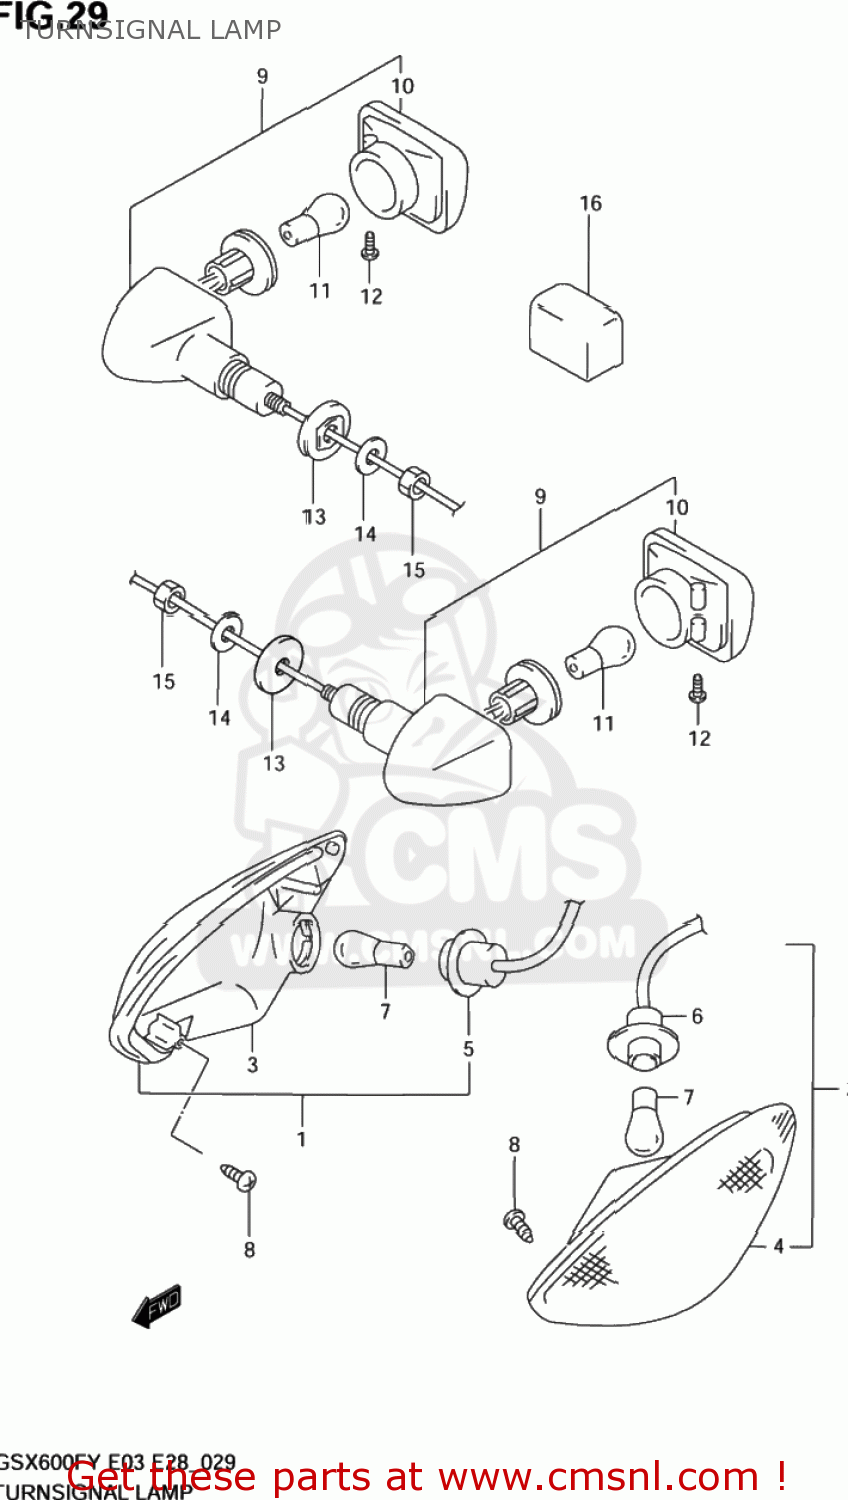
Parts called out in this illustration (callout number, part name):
1	LAMP ASSY,FR TURN SIGNAL,R
2	LAMP ASSY,FR TURN SIGNAL,L
3	LAMP UNIT,R
4	LAMP UNIT,L
5	SOCKET & CORD
6	SOCKET & CORD
7	BULB(12V21W)
8	SCREW
9	LAMP ASSY,RR TURNSIGNAL,R
10	LAMP UNIT
11	BULB(12V21W)
12	SCREW
13	SPACER,RR TURNSIGNAL
14	WASHER(10.5X30X2.3)
15	NUT
16	RELAY ASSY,TURNSIGNAL LAMP
